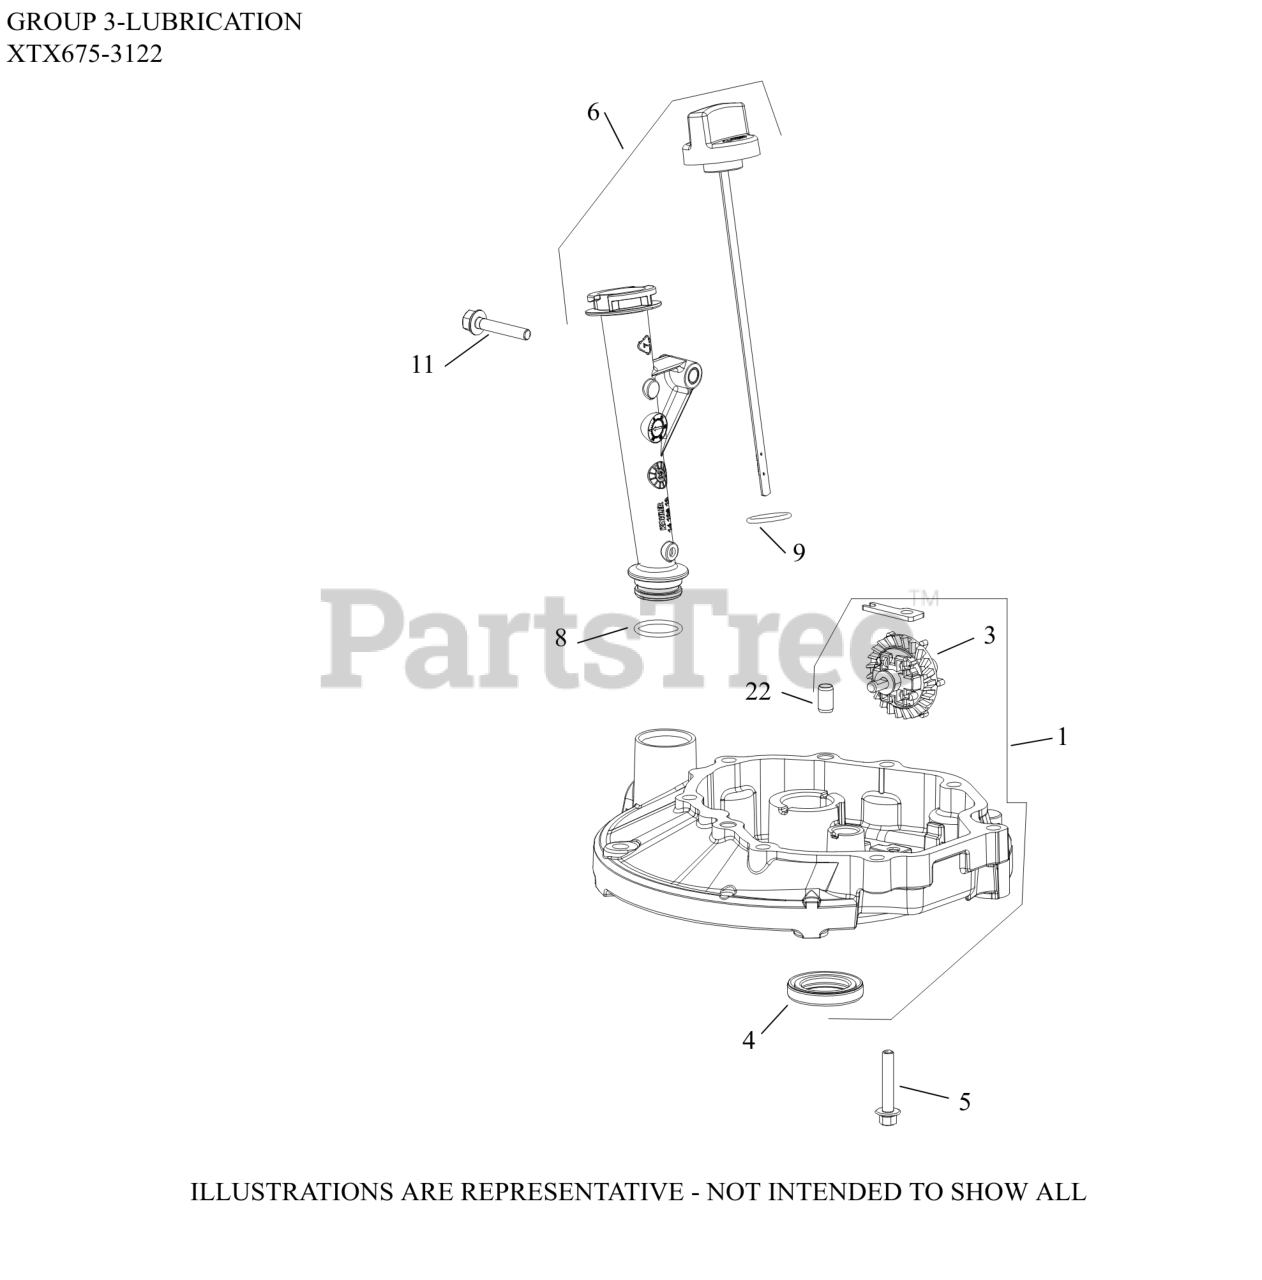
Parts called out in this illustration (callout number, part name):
1	KIT, OIL PAN
3	GEAR ASSEMBLY, GOVERNOR
5	SCREW, HEX FLANGE (M6)-(#25086434S)
6	TUBE ASSEMBLY OIL FILL
8	O-RING, OIL FILL TUBE
9	O-RING (CAP)
11	SCREW, HEX FLANGE (M6)-(#25086435S)
22	PIN, DOWEL (8mm)
